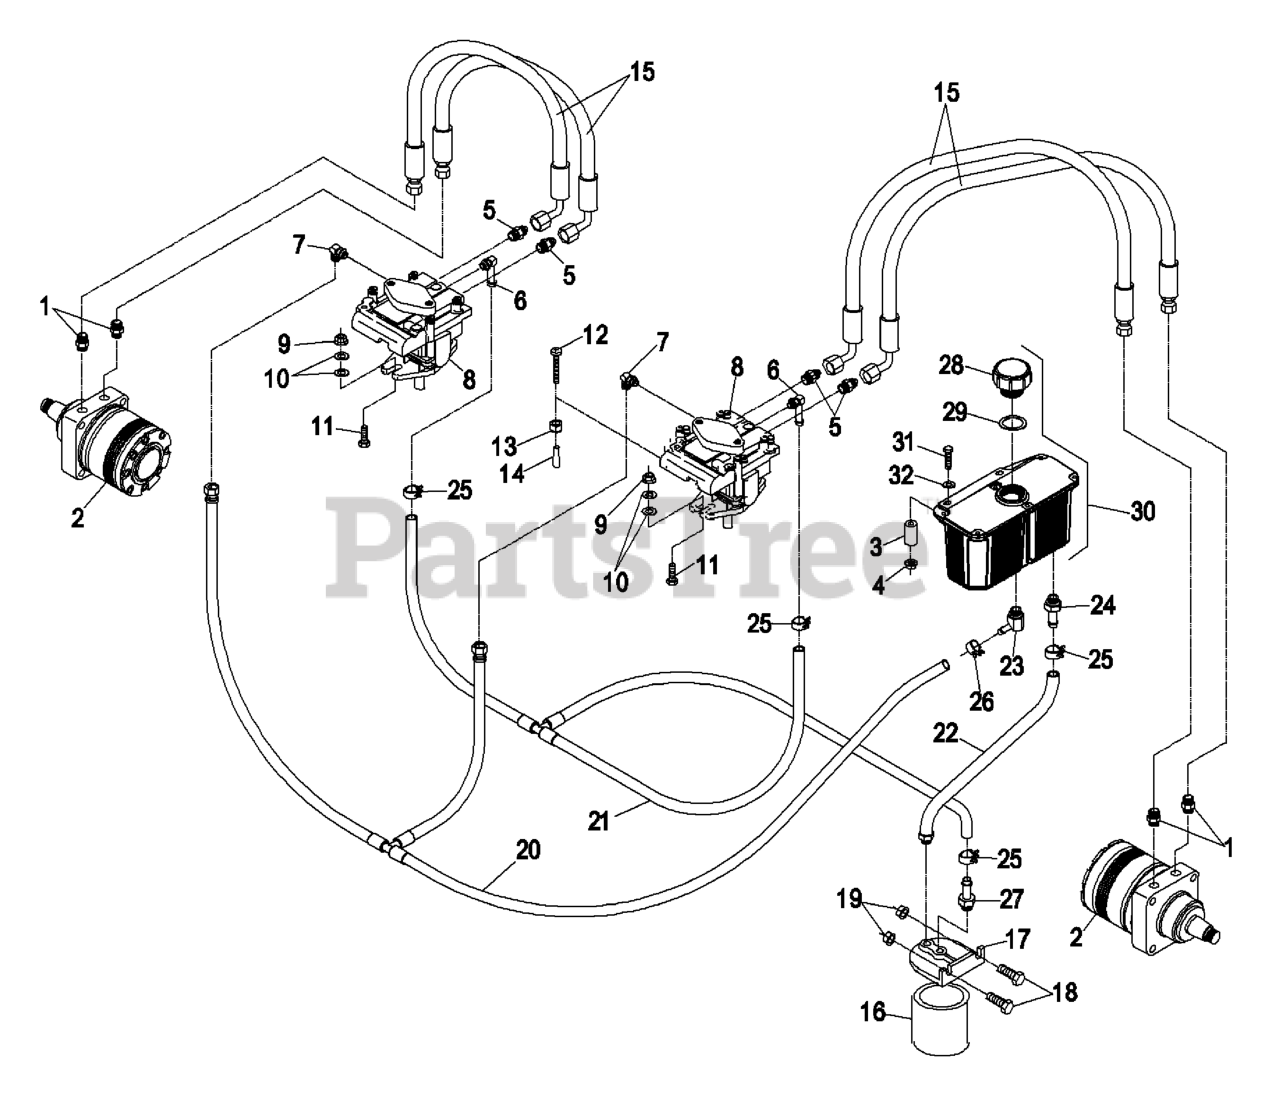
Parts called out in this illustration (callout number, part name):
1	FITTING-STRAIGHT
2	HYD MOTOR ASM
5	FITTING-STRAIGHT
6	FITTING
7	FITTING-90 DEG
9	NUT-HHF, WHIZ
10	WASHER-FLAT
11	SCREW-HH
13	NUT-LOCK, NI
14	GRIP-VALVE, DUMP
15	HOSE-PRESSURE, HIGH
18	SCREW-HH
20	HYD HOSE ASM
21	HYD HOSE ASM
22	HYD HOSE ASM
23	ELBOW-45 DEG
24	ADAPTER-STRAIGHT
25	CLAMP-HOSE
26	CLAMP-HOSE
27	FITTING-STR
28	Cap-Reservoir, HYD
29	GASKET-CAP
30	HYD RESERVOIR ASM
31	SCREW-HH
32	WASHER-FLAT
